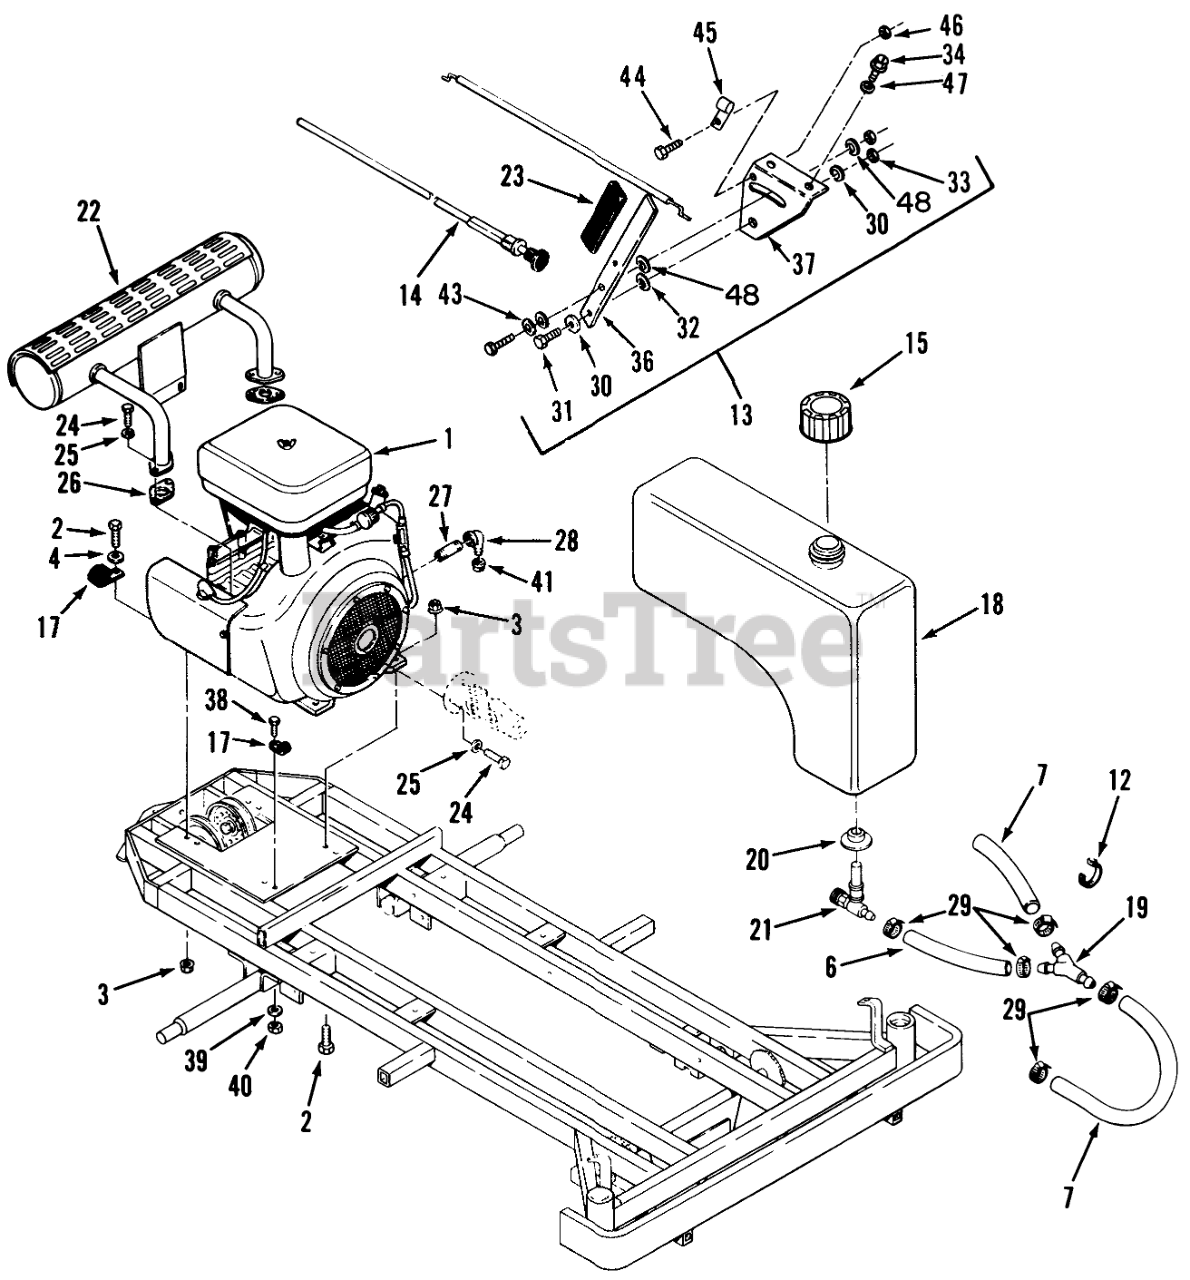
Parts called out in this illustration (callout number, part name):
1	Tire-Turf Tray, Front 12 X 7.5-8
2	BOLT
3	NUT
4	Washer
6	Hose5"
7	Fuel Line (29.5")
12	TIE-PLASTIC
13	Control-Throttle (Incl. Items #30 thru 33, 36 & 37)
14	CABLE-CHOKE
15	GAS CAP ASM
17	CLIP
18	Tank-Fuel (Incl. Items #20 & 21)
19	FITTING-FUEL 45-Y
20	BUSHING
21	VALVE-FUEL
22	MUFFLER
23	GRIP BRAKE20258-K
24	Bolt
25	Lockwasher
26	Exhaust Gasket
27	Pipe
28	STREET-ELBOW 90 DEG
29	Clamp
30	WASHER-FLAT
31	SCREW-HH
32	WASHER NYLON
34	SCREW-HH
35	Nut
36	Handle
37	Bracket & Cable-Throttle
38	Bolt
39	WASHER 5/16 SAE
40	Nut
41	Cap
42	Manual-Toro Power Plus Service
43	WASHER-SPRING DISC
44	Screw
45	CLIP BOWDEN WIRE
46	HEX NUT 10-32 E.S.
47	WASHER-LOCK
48	FRICTION WASHER
